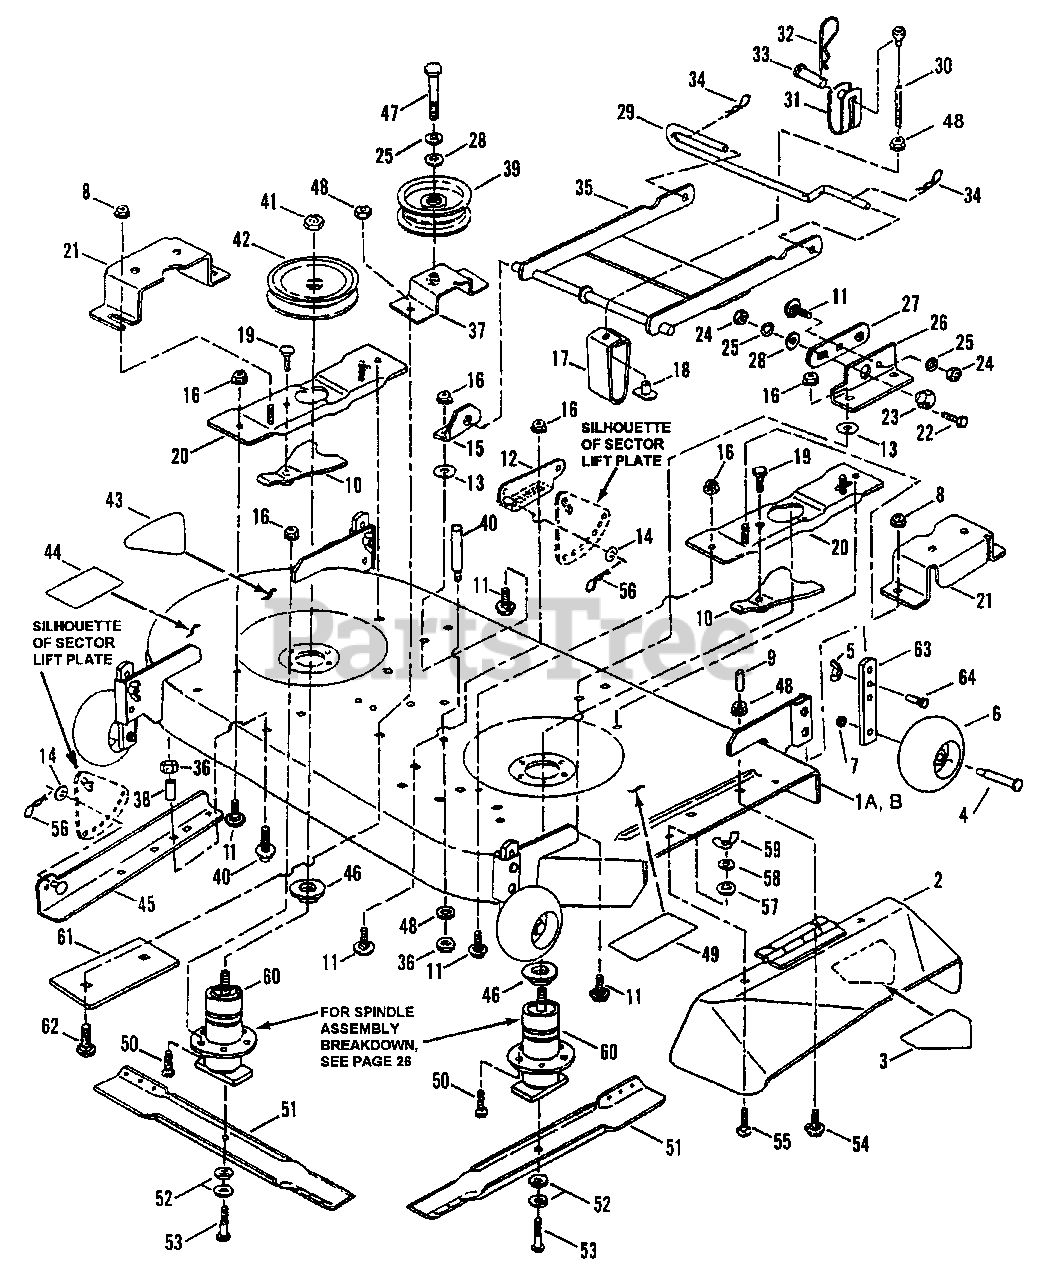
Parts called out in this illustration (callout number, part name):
1A	ASSEMBLY, 42" Cutting Deck
1B	ASSEMBLY, 42" Cutting Deck
2	DEFLECTOR, Side Discharge
3	DECAL - DANGER
4	BOLT, Gage Wheel
5	NUT, 3/8-16 Wing
6	WHEEL, Gage
7	NUT, 3/8-16 Hex Center Lock, Grade 5 or B
8	NUT, 5/16-18 Hex Flange Lock, Grade 5
9	CAP, Vinyl
10	ASSEMBLY, Spindle Lock
11	BOLT, 3/8-16 x 3/4" Carriage, Grade 2
12	BRACKET, Lift (Right Side)
13	WASHER, 3/8" Flat
14	WASHER, 3/8" Flat
15	BRACKET, Front Hanger (Left Side)
16	NUT, 3/8-16 Hex Flange Lock
17	BRACKET, Front Lift Arm Hanger
18	T-NUT, 5/16-18 Thread
19	BOLT, 3/8-16 x 1" Hex Flange Lock
20	ASSEMBLY, Spindle Brace
21	GUARD, Pulley
22	SCREW, 3/8-16 x 1" Hex Head Cap, Grade 5
23	ECCENTRIC, Leveling
24	NUT, 3/8-16 Hex
25	WASHER, 3/8 Split Lock
26	BRACKET, Front (Right Side)
27	LINK, Adjustment
28	WASHER, 3/8" Flat
29	PIN, Deck Hanger
30	CABLE, Deck Lift
31	CLEVIS, Lift Cable
32	PIN, Hair, 3/32 x 1-1/2"
33	PIN, Clevis, 3/8 x 1-1/16"
34	PIN, Hair, .148 x 2.62"
35	ASSEMBLY, Front Hanger
36	NUT, 3/8 - 16 Hex Center Lock, Grade 5 or B
37	BRACKET, Idler
38	SLEEVE, 1/2 x 13/32 x 3/8"
39	PULLEY, Idler 4-1/8"
40	BOLT, 3/8-16x1-1/2" Hex Flange Lock, Grade 5
41	NUT, 3/4-16 Hex Jam
42	PULLEY, Spindle
43	DECAL, 42" Deck
44	DECAL - CAUTION (Rotating Blades)
45	BRACKET, Deck Lift (Left Side)
46	WASHER, Spindle
47	BOLT, 3/8-16 x 1-3/4" Hex Flange Lock
48	NUT, 5/16-18 Hex Flange Lock, Grade 5
49	DECAL - CAUTION (Deflector in Place)
50	BOLT, 3/8-16 x 3/4" Hex Flange Lock
51	BLADE, 21" Cutter
52	WASHER, Cone, 13/32 x 1-13/32" Diameter
53	SCREW, 3/8-24 x 1-1/4" Hex Head Cap, Grade 5
54	BOLT, 5/16-18 x 1" Short Neck Carriage, Grade 5
55	BOLT, 5/16-18 x 5/8" Carriage, Grade 5
56	PIN, Hair, 3/32 x 1-1/2"
57	RETAINER, 5/16" Bolt
58	WASHER, 5/16 Split Lock
59	WING-NUT, 5/16-18
60	ASSEMBLY, Spindle
61	PLATE, Support
62	SCREW, 5/16-18 x 1" Hex Head Cap, Grade 5
63	POST, Anti Scalp
64	SCREW, 3/8-16 x 1-1/4" Hex Head Cap Grade 5
